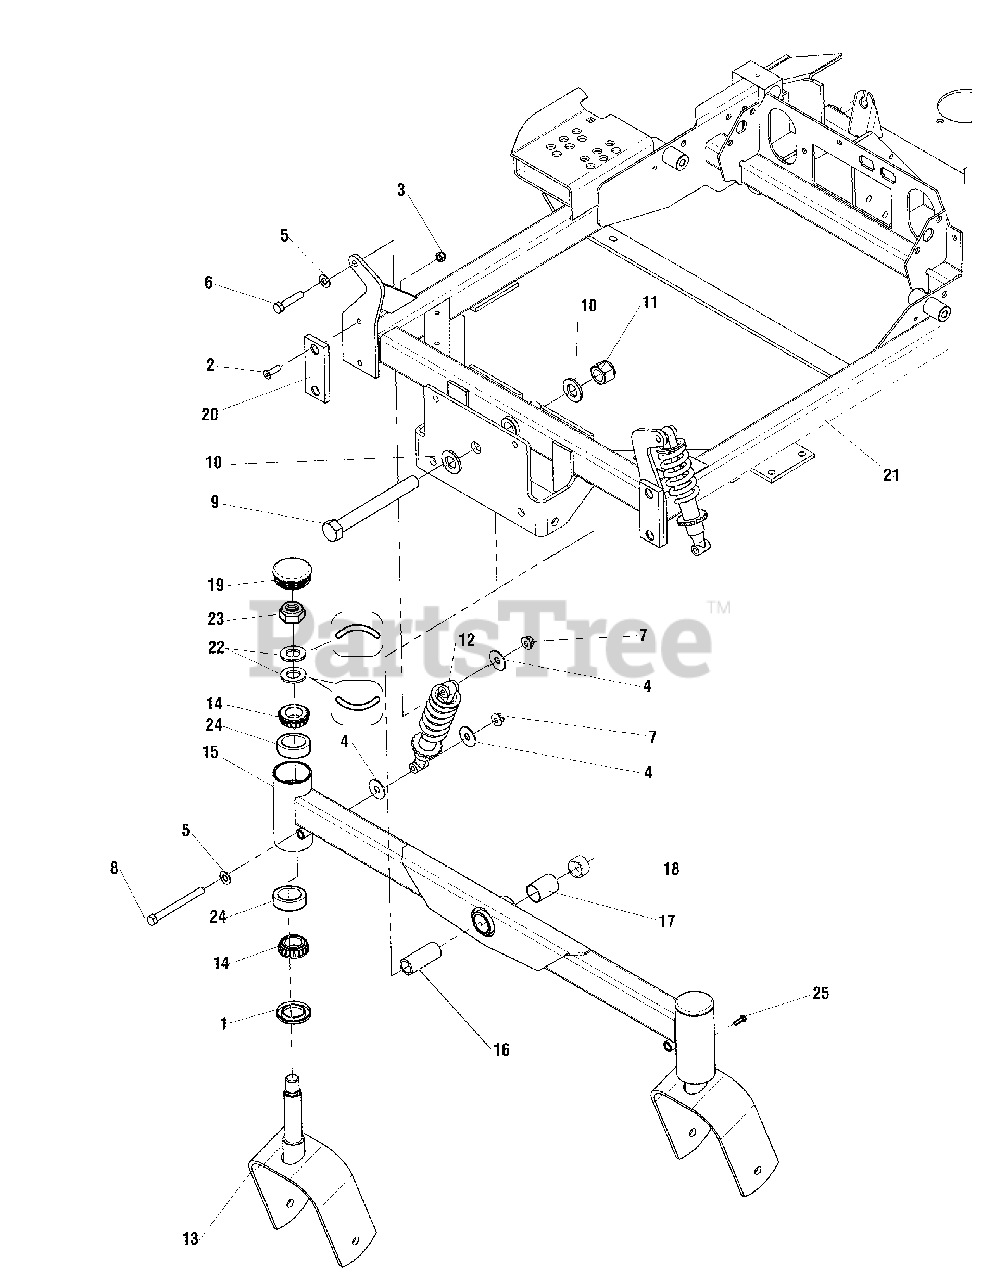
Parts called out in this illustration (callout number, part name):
1	SEAL, GREASE
2	SCREW, 5/16-18 X 1 PHILLIPS HD, BZ
3	NUT, 5/16-18 HEX NYLON LOCK
4	WASHER, 3/8 FENDER
5	WASHER, 3/8 SAE
6	BOLT, 3/8-16 X 1-3/4 GD5
7	NUT, 3/8-16 HEX NYLOCK FLANGE
8	BOLT, 3/8-16 X 4 GD5 YZ
9	BOLT, 3/4-16 X 6-1/2 YZ GD5
10	WASHER, 3/4 SAE
11	NUT, 3/4-16 HEX NYLON LOCK
12	SHOCK, SPRING ASSEMBLY
13	WELD, CASTER YOKE -ORG
14	BEARING, TAPERED ROLLER, 1
15	WELD, FRONT PIVOT
15	WELD, FRONT PIVOT - ORG
16	SPACER, .75 X 1.00 X 2.38
17	PIVOT BEARING, 1.00 X 1.125 OD X 1.50
18	PIVOT BEARING, 1.00 X 1.125 OD X .50
19	CAP, LOW PROFILE, STEEL
20	DECK FRICTION REDUCER PLATE
20	PAD, FRICTION
21	WELD, MAIN FRAME
22	WASHER, BELLEVILLE - 1.500 X .755
23	NUT, 3/4-16, HEX JAM NYLON LOCK
24	BEARING CUP (SV)
25	BOLT, 1/4-28 X 1/2, GD5 YZ
